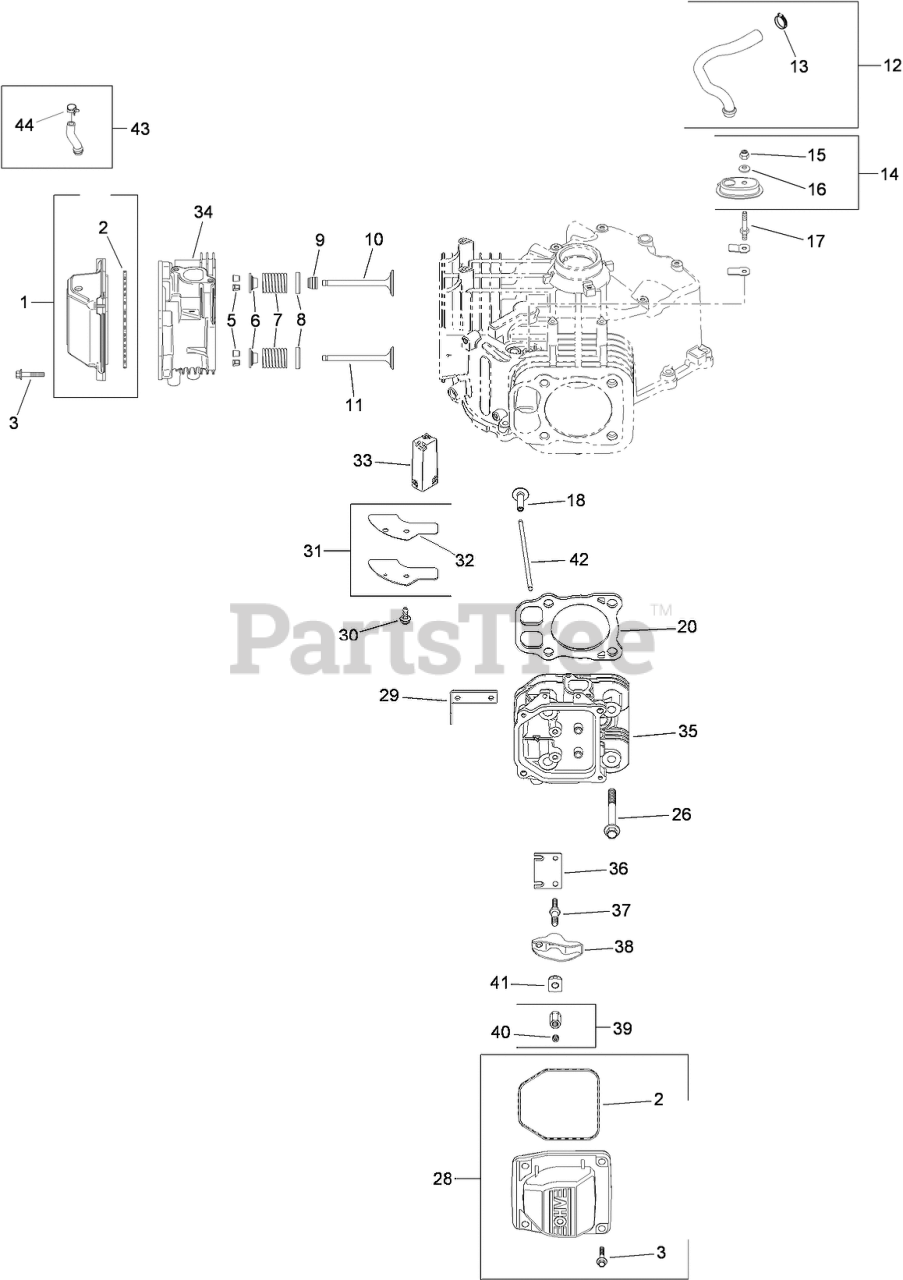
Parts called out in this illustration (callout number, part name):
1	BREATHER VALVE COVER KIT (INCLUDES 2 QTY 1])
2	O-RING (VALVE COVER)
3	SCREW-FLANGE (M6X1.0X30)
5	RETAINER KIT
6	CAP-SPRING, VALVE
7	SPRING-VALVE
8	RETAINER-SPRING
9	SEAL-STEM, VALVE
10	VALVE-INTAKE (STD)
11	VALVE-EXHAUST (STD)
12	BREATHER HOSE KIT (INCLUDES 13)
13	CLAMP-HOSE, SPRING (1/2)
14	BREATHER HOUSING KIT (INCLUDES 15, 16)
15	NUT-LOCK (M5X.8)
16	WASHER-SEALING
17	STUD-COVER, BREATHER
18	TAPPET KIT
20	CYLINDER HEAD GASKET KIT (INCLUDES 26QTY 4], 24 041 49-S, 24 153 27-S)
26	SCREW-FLANGE (M10X1.5X90)
28	PLAIN ROCKER COVER KIT (INCLUDES 2 QTY 1], 3 QTY 4])
29	STRAP-LIFTING
30	SCREW-FLANGE, THREAD FORMING (M6X1.0X16)
31	BREATHER COVER KIT (INCLUDES 32)
32	GASKET-COVER, BREATHER
33	FILTER-BREATHER
34	CYLINDER HEAD NO.1 ASM (INCLUDES EXHAUST MOUNTING HARDWARE)
35	CYLINDER HEAD NO.2 ASM (INCLUDES EXHAUST MOUNTING HARDWARE)
36	PLATE-GUIDE
37	STUD-ROCKER
38	ARM-ROCKER
39	HEX NUT ASM (INCLUDES 40)
40	SCREW-SET
41	PIVOT-ARM, ROCKER
42	ROD-PUSH (AFTER S/N 3633510943)
43	FUEL PUMP HOSE W/CLAMP KIT (INCLUDES 44)
44	CLAMP-HOSE
